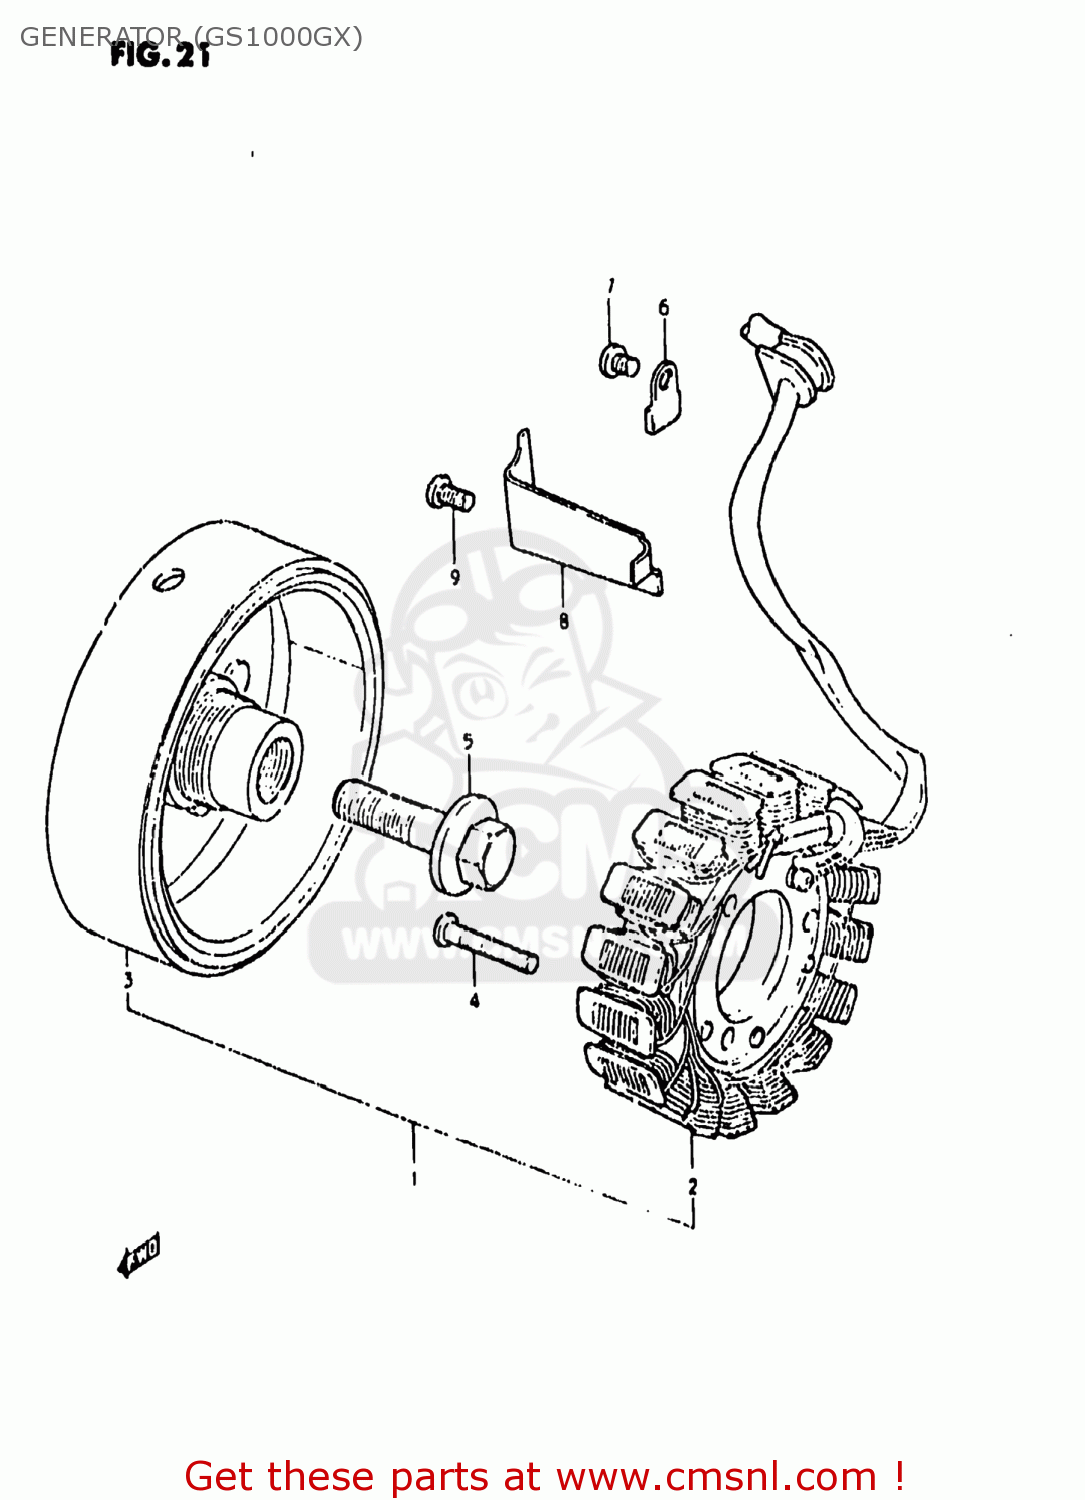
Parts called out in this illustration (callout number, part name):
1	GENERATOR ASSEMBLY
2	STATOR ASSEMBLY
3	ROTOR
4	SCREW 6X30
5	BOLT 12X45
6	CLAMP,GENERATOR LEAD WIRE
7	SCREW
8	CLAMP,GENERATOR LEAD WIRE
9	SCREW
